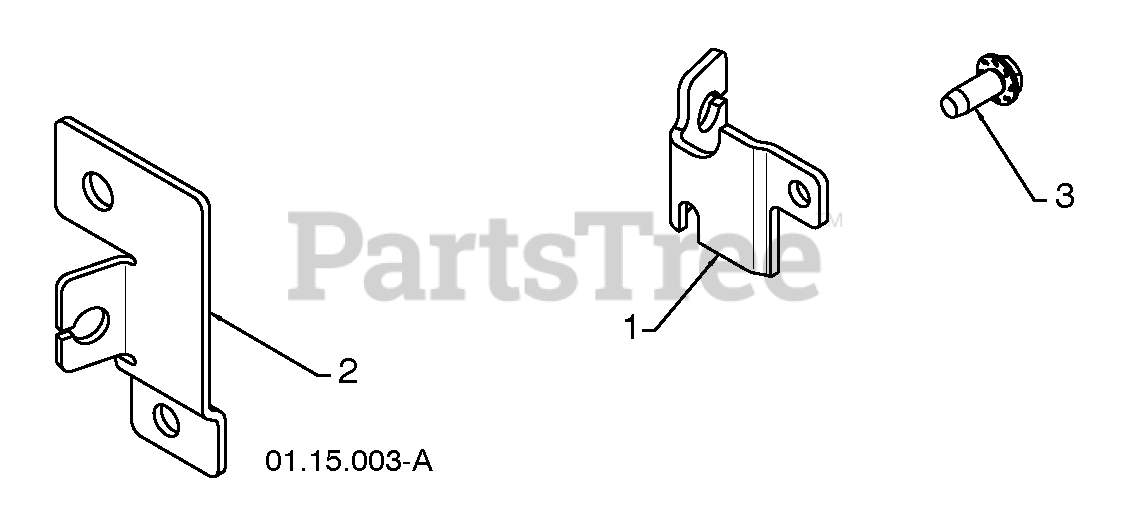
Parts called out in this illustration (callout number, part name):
1	CABLE BRACKET LH
2	CABLE BRACKET RH
3	SCREW 1/4-20 X .625
